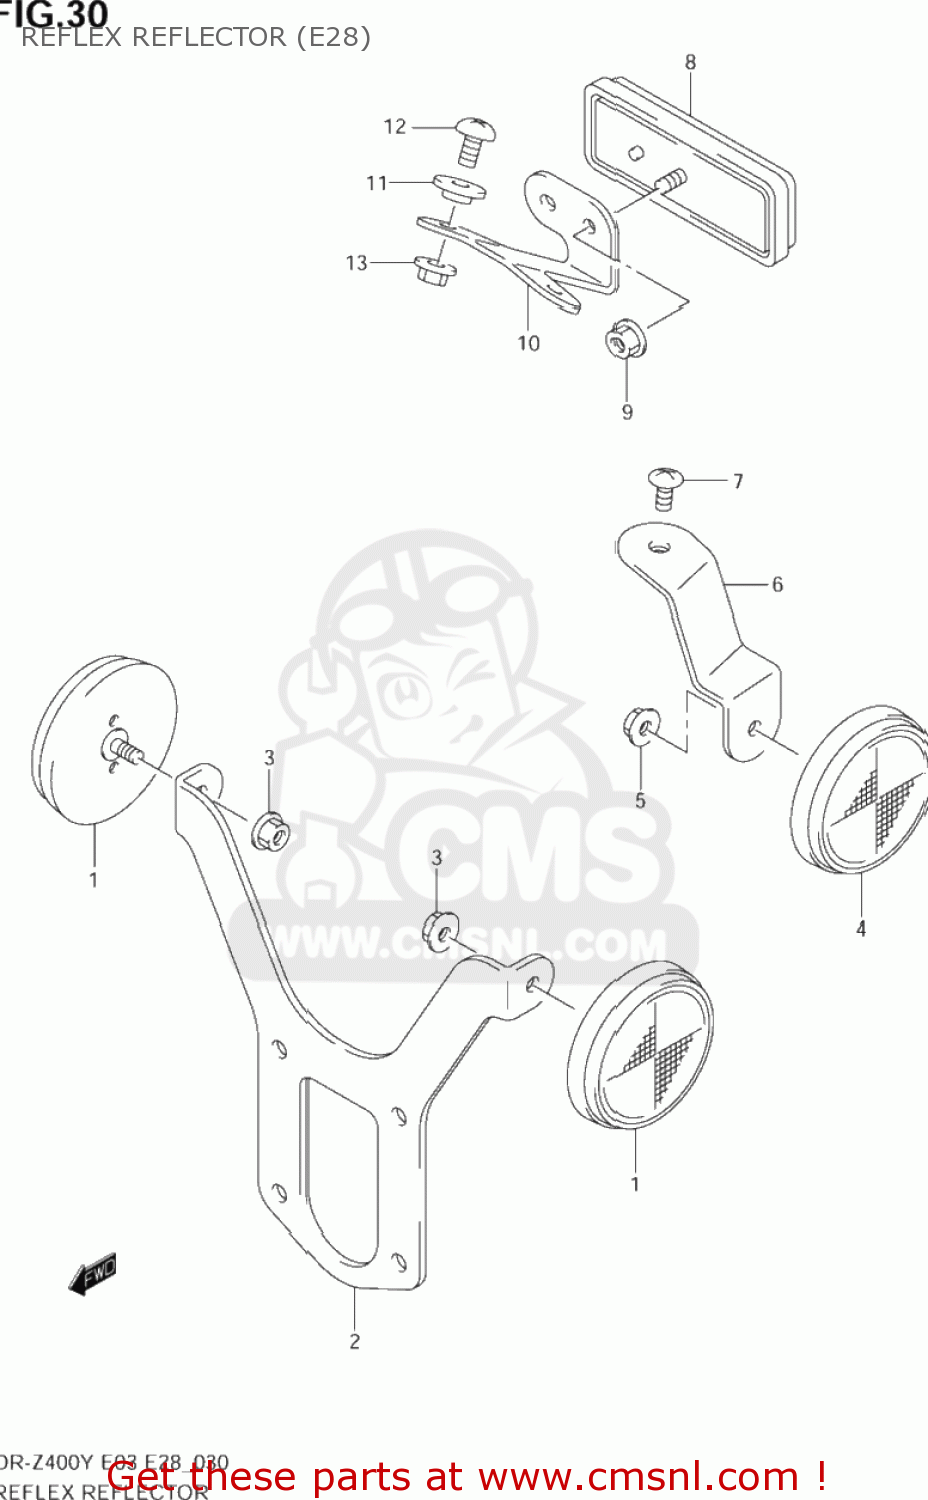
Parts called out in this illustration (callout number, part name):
1	REFLECTOR,REFLEX FR
2	BRACKET,FR SIDE RR
3	NUT
4	REFLECTOR ASSY,RR SIDE
5	NUT
6	BRACKET,RR SIDE RR,R
7	SCREW 6X12
8	REFLECTOR ASSEMBLY,REAR
9	NUT
10	BRACKET,RR RR
11	WASHER(5.5X16X1.2)
12	SCREW 5X12
13	NUT
